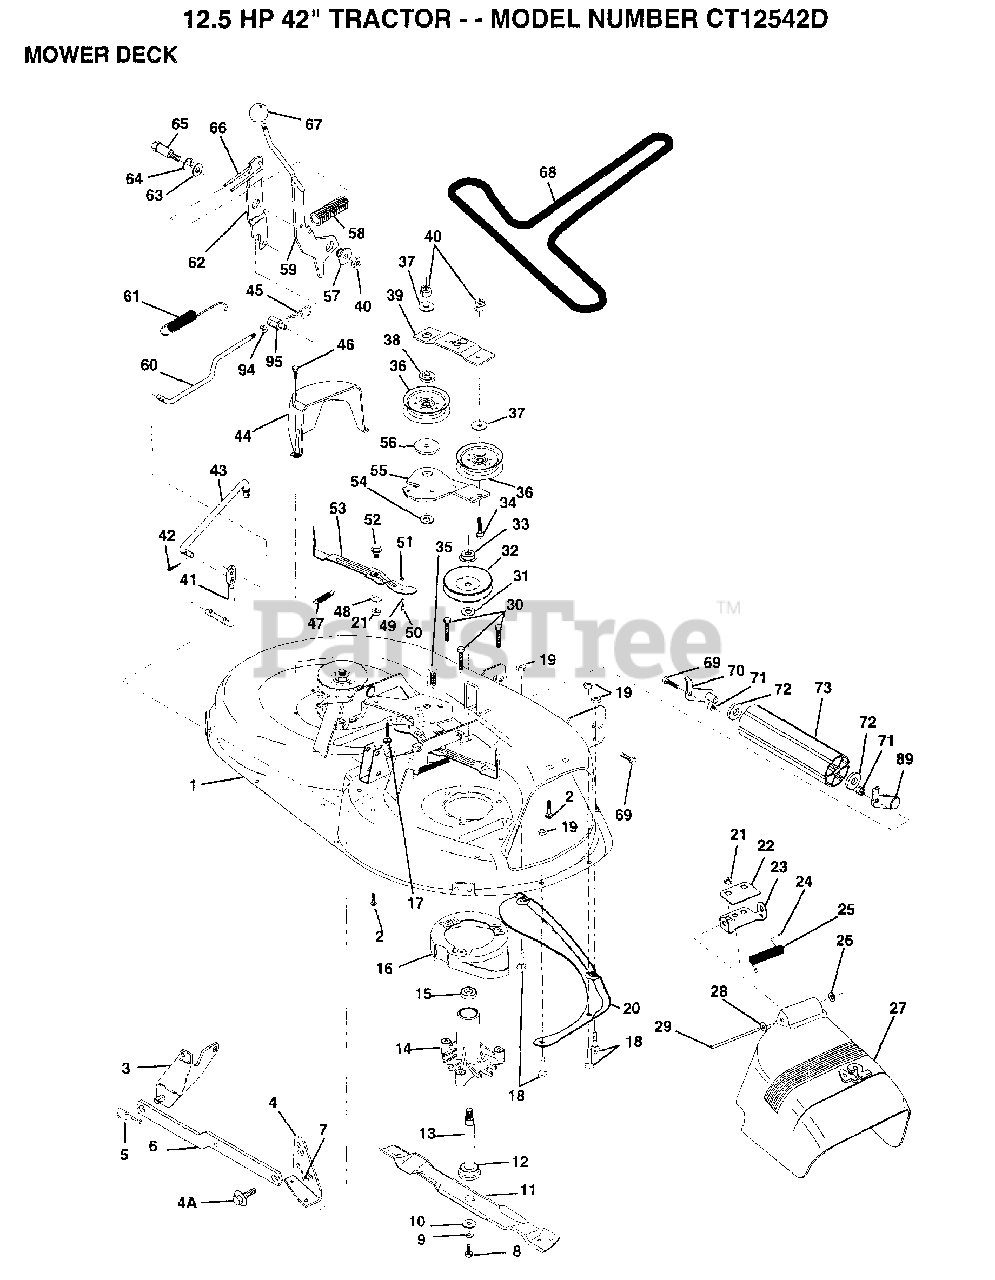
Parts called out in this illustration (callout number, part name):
2	BOLT
3	BRKT ASM SWAY BAR
4	BRKT DECK SW BAR
4A	BOLT SHD 5/16-18
7	NUT
8	BLADE BOLT
10	WASHER.HARD.BLADE
11	"BLADE.42"" MULCHER"
12	BEARING.BALL
14	HSG ASM MANDREL
15	BEARING
17	BOLT CARRIAGE
18	BOLT
19	NUT
22	STIFFENER BRKT
23	DEFLECTOR BRKT
24	CAP-SLEEVE LT
25	SPRING TORSION
26	NUT PUSH M
27	DEFLECTOR.SHIELD
28	WASHER
29	HINGE ROD
31	WASHER
34	BOLT
35	XMAS TREE FASTNER
36	FLAT IDLER PULLEY
37	WASHER GT
38	RETAINER SPACER
39	IDLER ARM STIFF
40	NUT
41	PIVOT ROD
43	CLUTCH ROD SECOND
44	GUARD MAND LH BLK
45	RETAINER M
46	SCREW.1/4-20X5/8
47	SPRING EXTENSION
48	HARD SMALL WASHER
50	SHOULDER BOLT
51	LOCKNUT
52	BOLT.SHLD.5/16-18
53	BRAKE PAD ARM ASM
54	HARDENED WASHER
55	IDLER ARM
56	SPACER RETAINER
57	BUSHING
61	RETURN SPRING
62	CLUTCH ARM SECOND
63	WASHER
64	RING
65	SHOULDER BOLT
66	SPRING KEEPER
68	BELT-V.92.4.MWR
69	BOLT
72	WASHER
94	NUT
95	TRUNION
